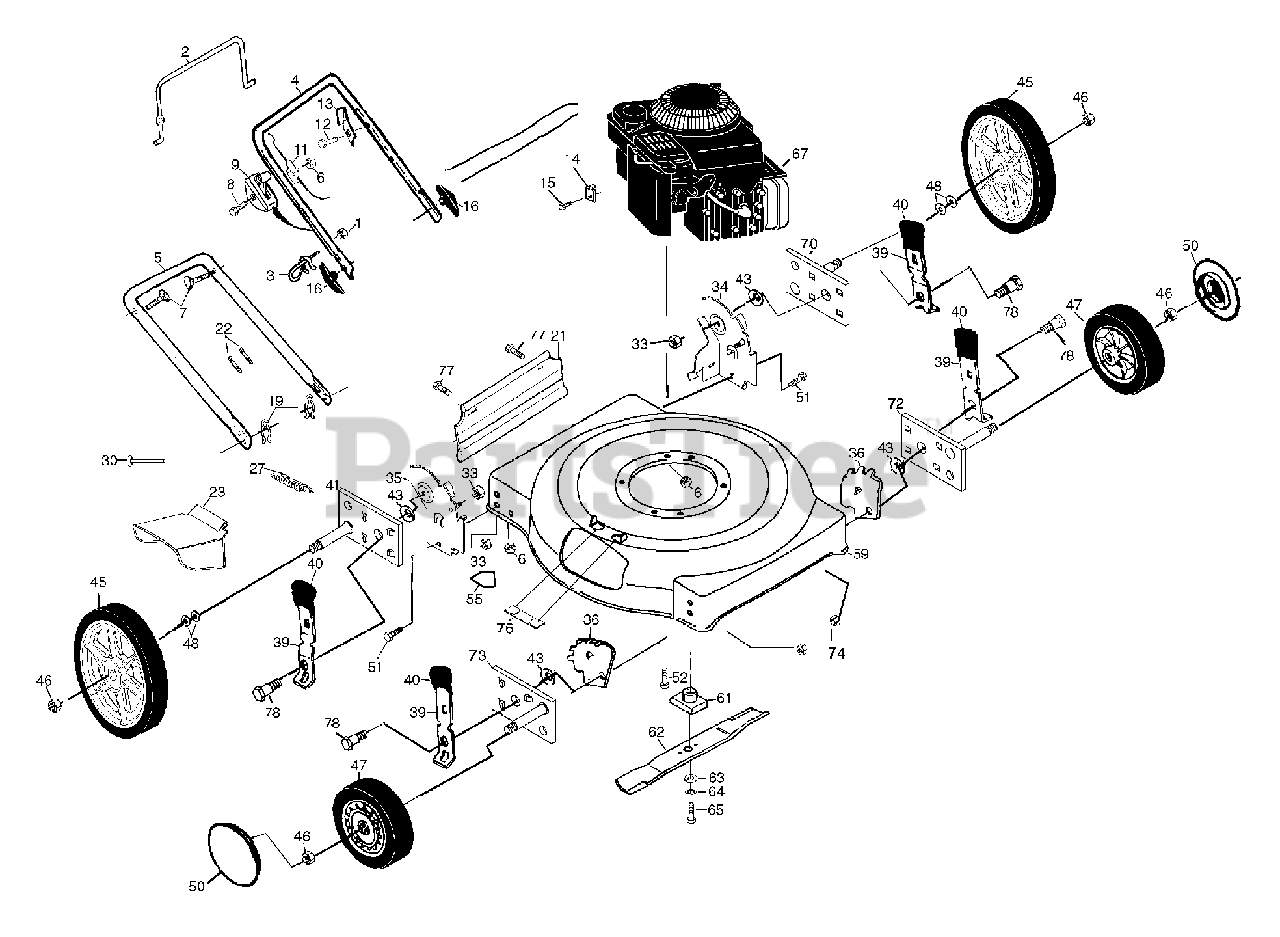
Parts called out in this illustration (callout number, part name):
1	Locknut 1/4-20
2	Control Bar
3	Rope Guide
4	Upper Handle
5	Lower Handle
6	Locknut 1/4-20
7	Handle Bolt 5/16-18
8	Hex Washer Head Screw 1/4-20 x 2-1/8
9	Throttle Control
11	Engine Zone Control Cable
12	Hex Washer Head Screw #10-24 x 1/2
13	Up-Stop Bracket
14	Cable Clamp
15	Screw #10 x 5/8
16	Handle Knob
19	Hairpin Cotter
21	Rear Deflector
22	Wire Tie
23	Discharge Guard
27	Torsion Spring
30	Hinge Rod
33	Locknut 5/16-18
34	Wheel Bracket Support (Left)
35	Wheel Bracket Support (Right)
36	Wheel Bracket Adjuster
39	Selector Spring
40	Selector Knob
41	Axle Arm Assembly (RR)
43	Washer
45	Wheel Assembly (Rear)
46	Locknut 1/16-18
47	Wheel Assembly (Front)
48	Washer
50	Hubcap
51	Hex Head Bolt 5/16-18
52	Hex Head Thread Rolling Screw 3/8-16 x 1
55	Danger Decal
59	Lawn Mower Housing
61	Blade Adapter
62	22" Blade
63	Hardened Washer
64	Helical Lockwasher 3/8
65	Screw Hex Head 3/8-24 x 1-3/8 (Grd. 8)
70	Axle Arm Assem.(LR)
72	Axle Arm Assm. ((LF)
73	Axle Arm Assm. (RF)
74	Nut
76	Clip. Closeout
77	Screw
78	Shoulder Bolt
